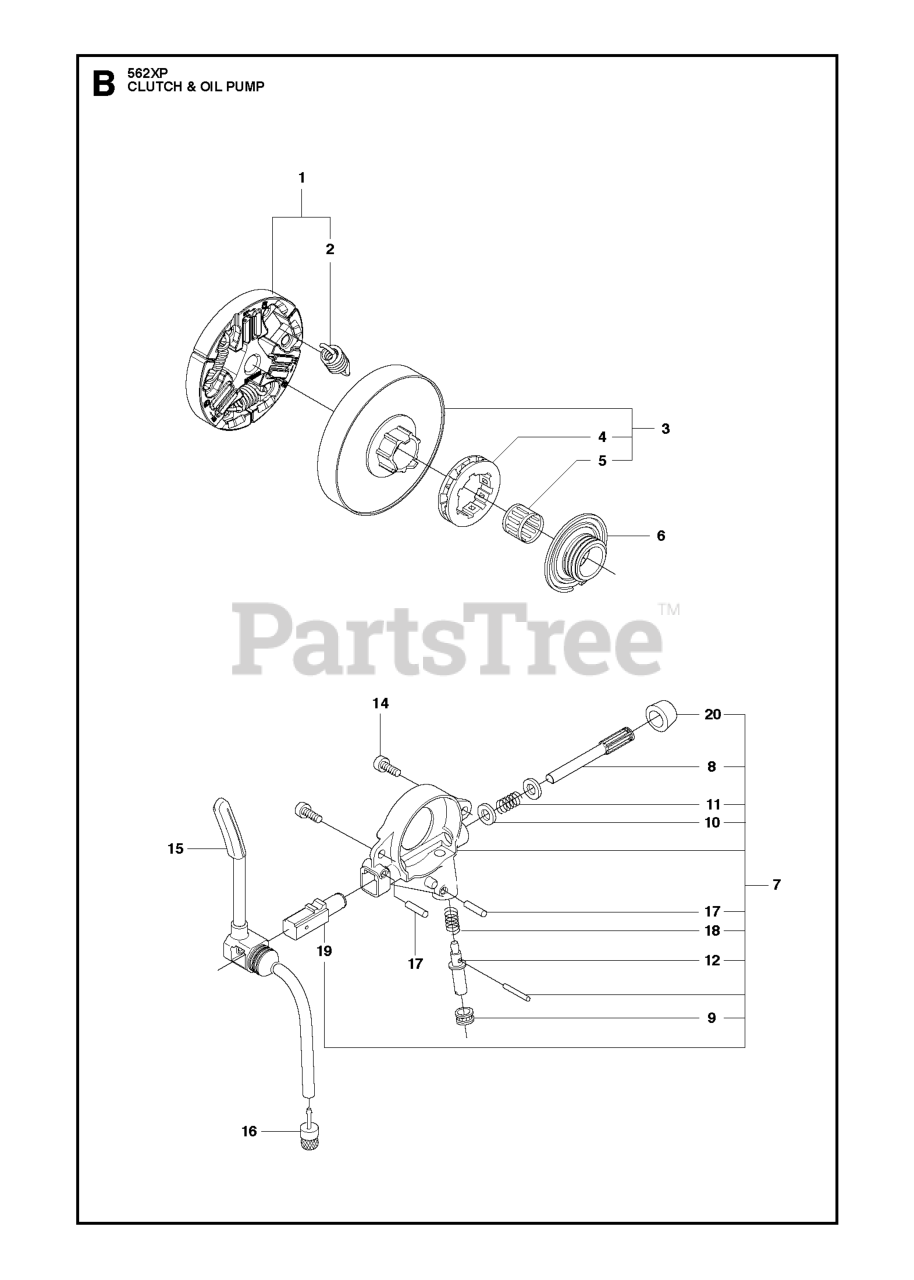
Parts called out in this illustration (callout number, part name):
1	CLUTCH ASSY 60CC
2	CLUTCH SPRING
3	CLUTCH DRUM ASSY RIM .325"7T
3	CLUTCH DRUM 3/8" 7T
4	RIM SPROCKET 7T .325
4	68210 RIMSPROCKET
5	SUPPORT BUSHING
6	RP WORM WHEEL
7	OIL PUMP ASSY
8	PUMP PISTON
12	ADJUSTING SCREW
14	SCREW ITXSCM M4X15 T27 12.9 T
16	OIL PLUMMET
19	PUMP CYLINDER
20	SEALING PLUG GREEN
